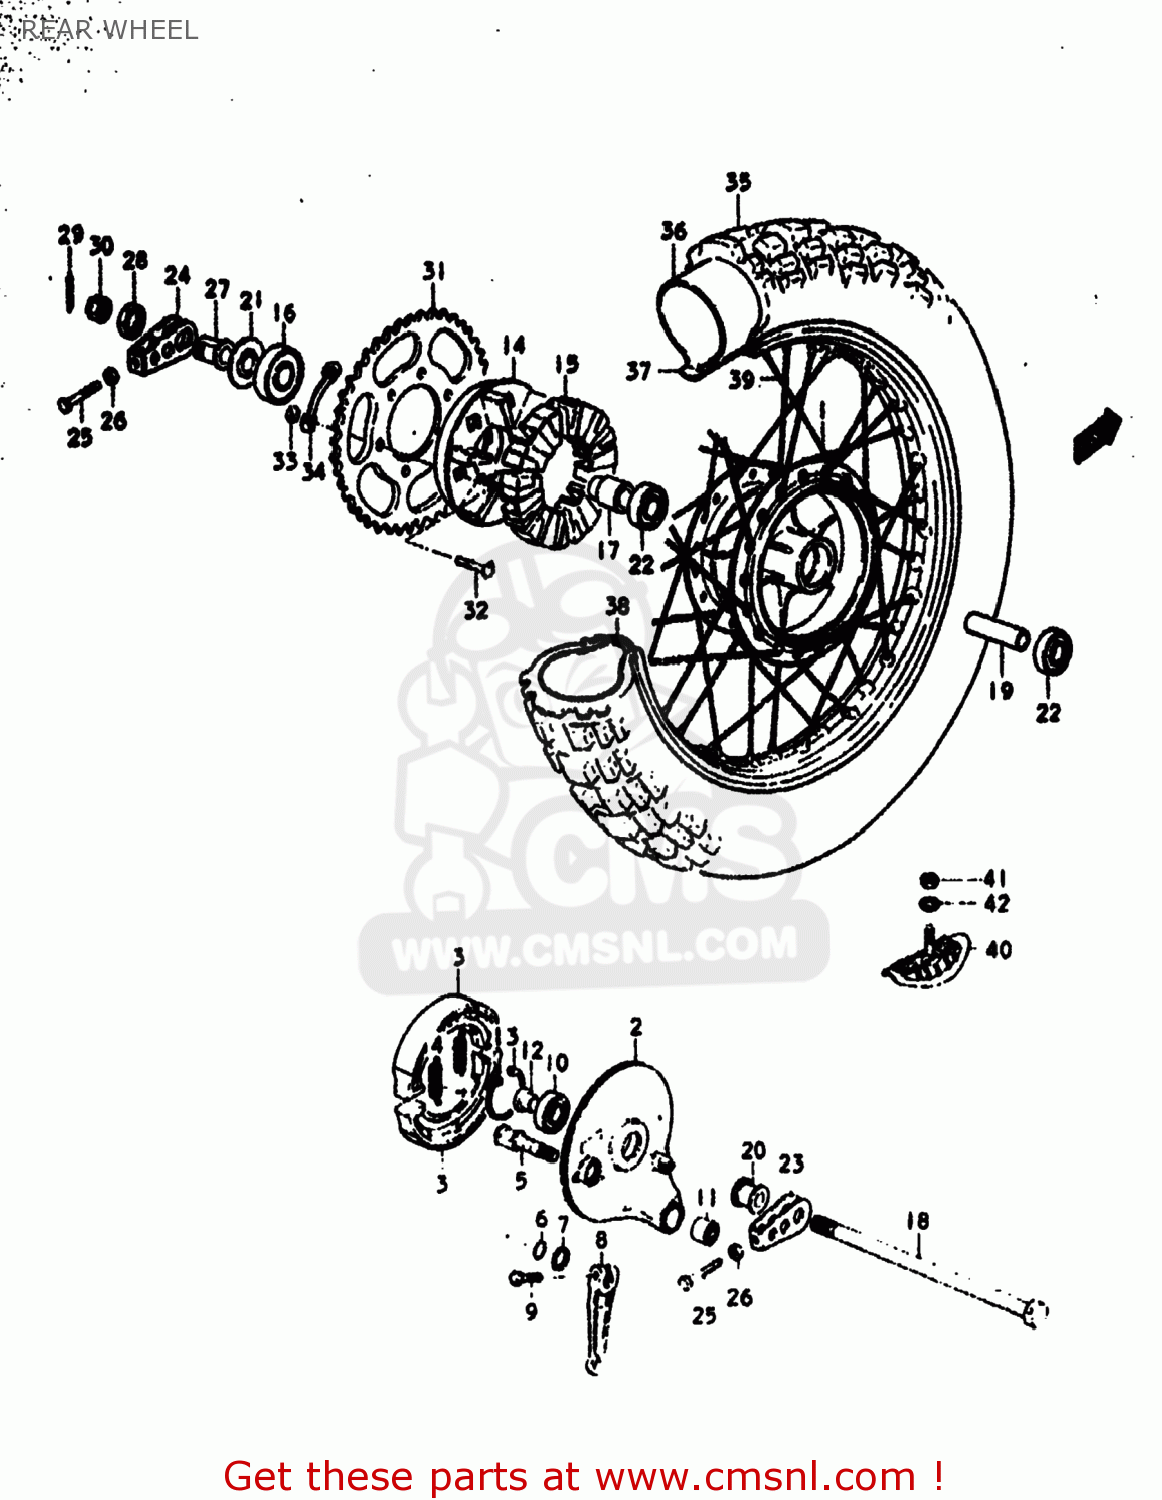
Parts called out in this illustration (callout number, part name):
1	DRUM,REAR HUB
2	PANEL,REAR HUB
3	SHOE,BRAKE
4	SPRING
5	CAM,FRONT BRAKE
6	O-RING,BOSS
7	WASHER (15X24X1.6)
8	LEVER,REAR BRAKE CAM
9	BOLT
10	BEARING
11	BUSH
12	SPACER,REAR HUB PANEL
13	CIRCLIP,42MM
14	DRUM,REAR SPROCKET MOUNT
15	CUSHION,REAR DRUM
16	BEARING
17	SPACER,REAR HUB BEARING
18	AXLE,REAR
19	SPACER (15.3X21.7X82)
20	SPACER,AXLE,RIGHT
21	SPACER,REAR AXLE,RIGHT
22	BEARING
23	ADJUSTER,CHAIN
24	ADJUSTER,CHAIN
25	BOLT
26	NUT
27	SPACER,CHAIN ADJUSTER
28	NUT
29	PIN 30X40
30	NUT
31	SPROCKET,REAR
32	BOLT(8X33.5)
33	NUT
34	WASHER
35	TIRE
36	TUBE ASSEMBLY,WHEEL,INNER
37	PROTECTOR,WHEEL,INNER
38	RIM,REAR WHEEL
39	SPOKE SET,REAR
40	STOPPER,BEAD
41	NUT
42	WASHER
